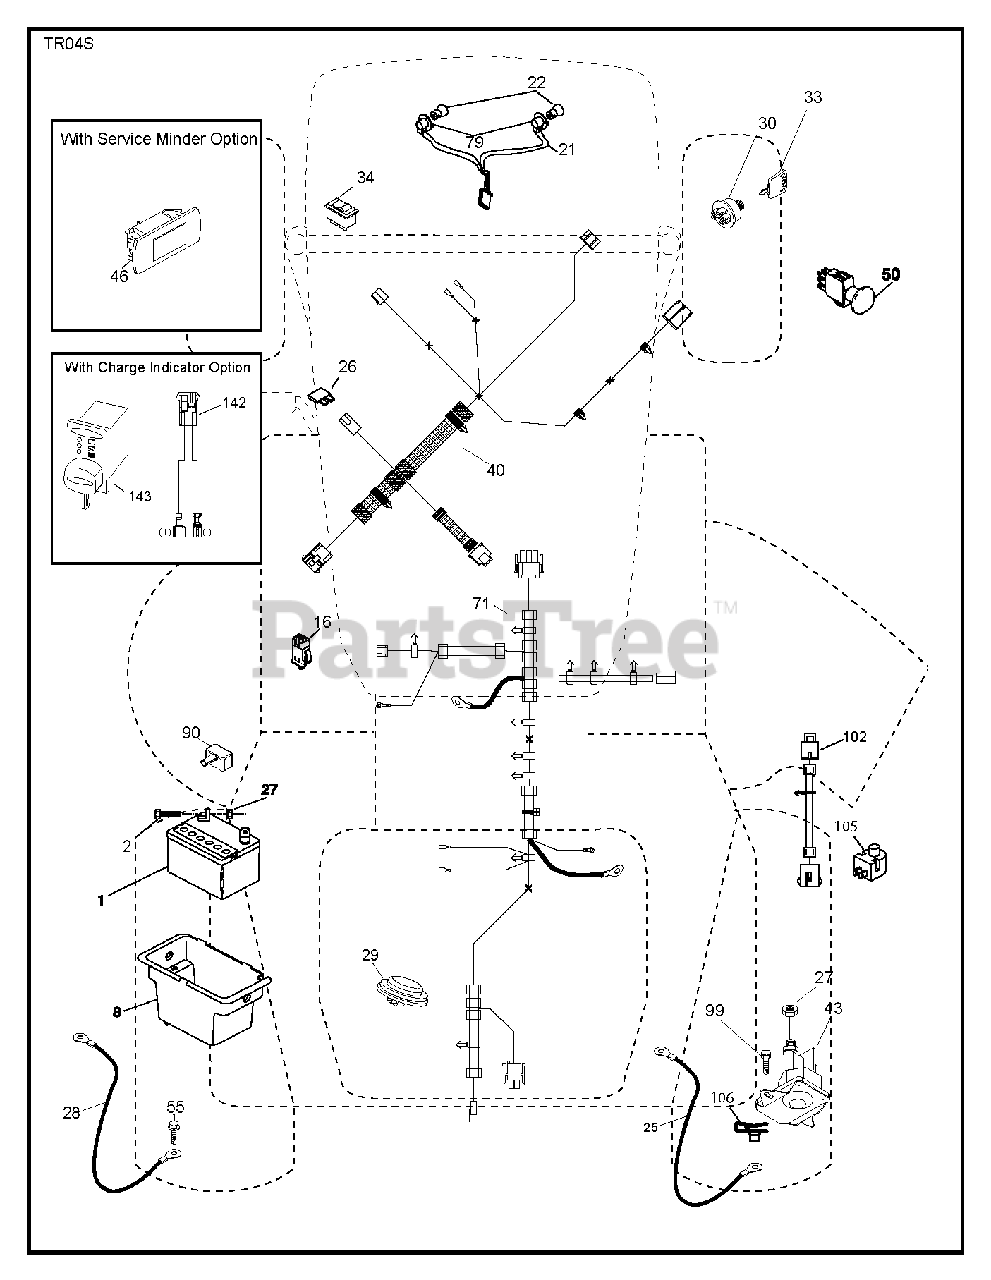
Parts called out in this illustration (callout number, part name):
1	Battery, Dry 30 Amp
2	BOLT.HEX.1/4.X.3/4.DICHROMATE
8	BOX.BATTERY.MNT.REAR.L
16	SWITCH INTERLOOK PUSH-IN
21	HARNESS.LIGHT W/4152J BULBS
25	CABLE.BATT.RED.8GA.17
26	FUSE 20AMP
27	NUT
28	CABLE.GROUND.REAR.BATTERY.8G
29	SWITCH.SEAT.DELTA.OPC.
30	SWITCH.IGN.DELTA.W.LGH.ROS
33	KEY.CHAIN.BLISTER.PACK.GEN.INT
40	HARNESS.DASH.RRBATT.EL.CHG
43	SOLENOID.W/BRASS.PLUNGER
46	GUAGE.SRVCMNDR.HRMTR.
50	RB PTO.SWITCH.8 TERMINAL.BLACK
55	SCREW 5/16"
71	HARNESS.CHASSIS.RRBATT.RDYSTRT
79	BULB HOLDER ASM.
90	COVER.TERMINAL.BATTERY
99	SCREW HEXWSHR 1/4-20X3/4
102	HARNESS PIGTAIL PCH TEX ROS
105	REVERSE SWITCH
106	1/4-20 U NUT
142	CHARGE.PORT.PIGTAIL HARNESS
143	CHARGE.PORT
